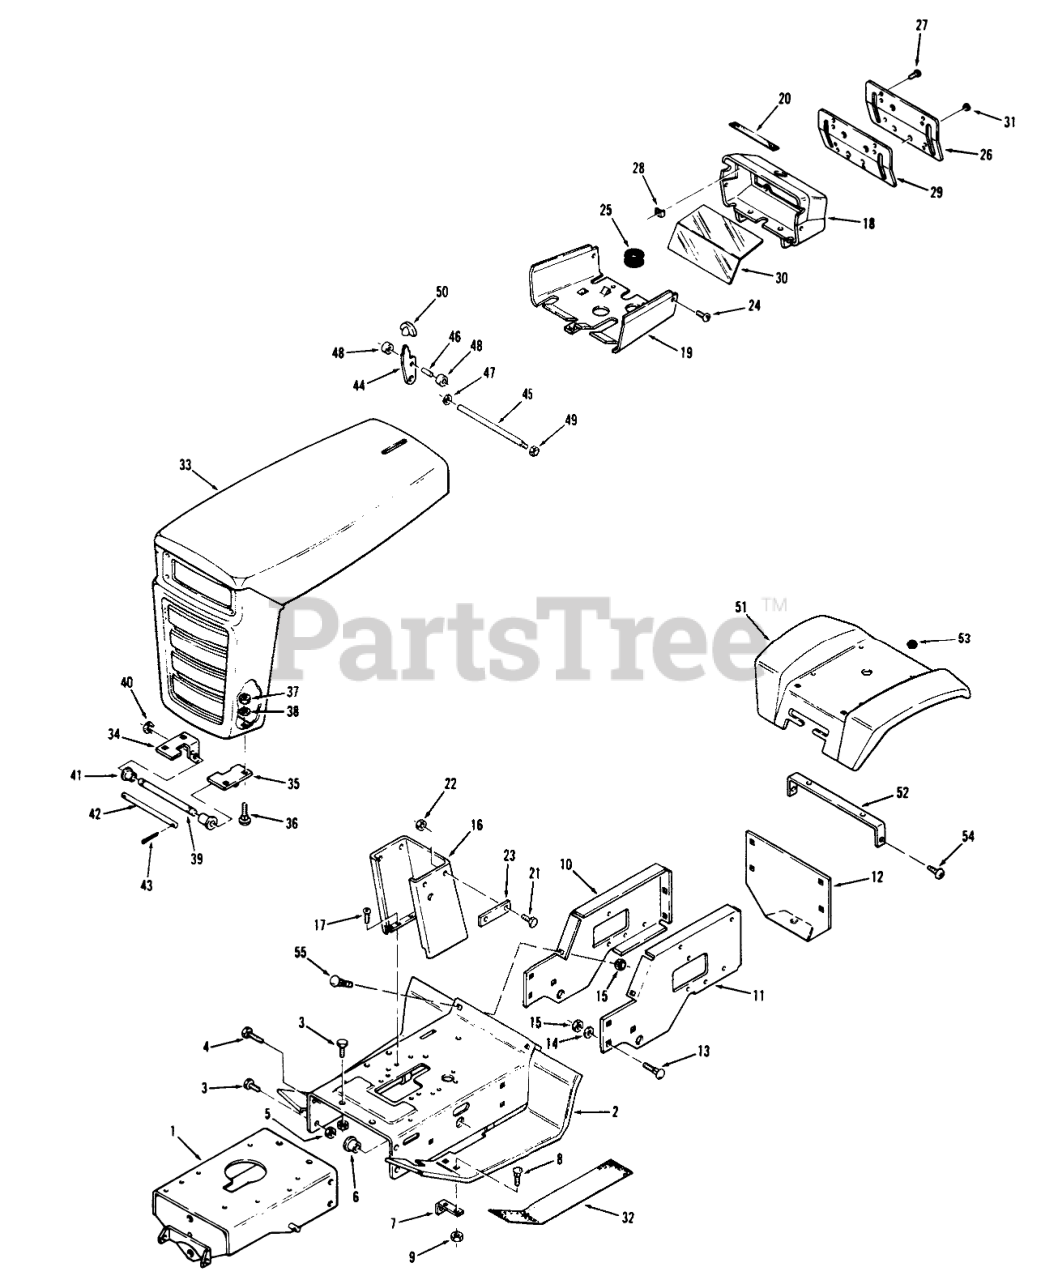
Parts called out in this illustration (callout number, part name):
1	Assy-Frame Front
2	Assy-Frame Center (W/Bushing)
3	Bolt
4	Bolt
5	Nut
6	Bushing
7	Bracket
8	Bolt
9	Nut
10	Panel-Side-R.H.
11	L.H. Side Panel
12	Panel-Rear
13	Bolt-Carriage
14	Washer
15	Nut
16	Thrust Washer
17	SCREW
18	Housing
19	Support-Tank
20	Tape
21	Screw
22	Nut
23	Spacer
24	Screw
25	Grommet
26	Dash Panel
27	SCREW BLACK
28	SPEED NUT
29	BACK UP PLATE
30	CONTROL PROTECTOR
31	PLUG BUTTON
32	PAD-FOOTREST
33	Assy-Hood & Grill
33	Hood
34	Bracket-Grill Pivot RH
35	Bracket-Grill Pivot LH
36	Bolt
37	Nut
38	WASHER 5/16 SAE
39	Rod-Pivot
40	RING-RETAINING
41	NYLINER BUSHING
42	ROD PIVOT STOP
43	Cotter Pin
44	LEVER HOOD LATCH
45	Rod Latch
46	SPIROL PIN
47	SPEED NUT
48	Roller
50	KNOB
51	Assy-Fender & Plate
52	Fender Support
53	Bushing
54	Bolt
55	Bolt
